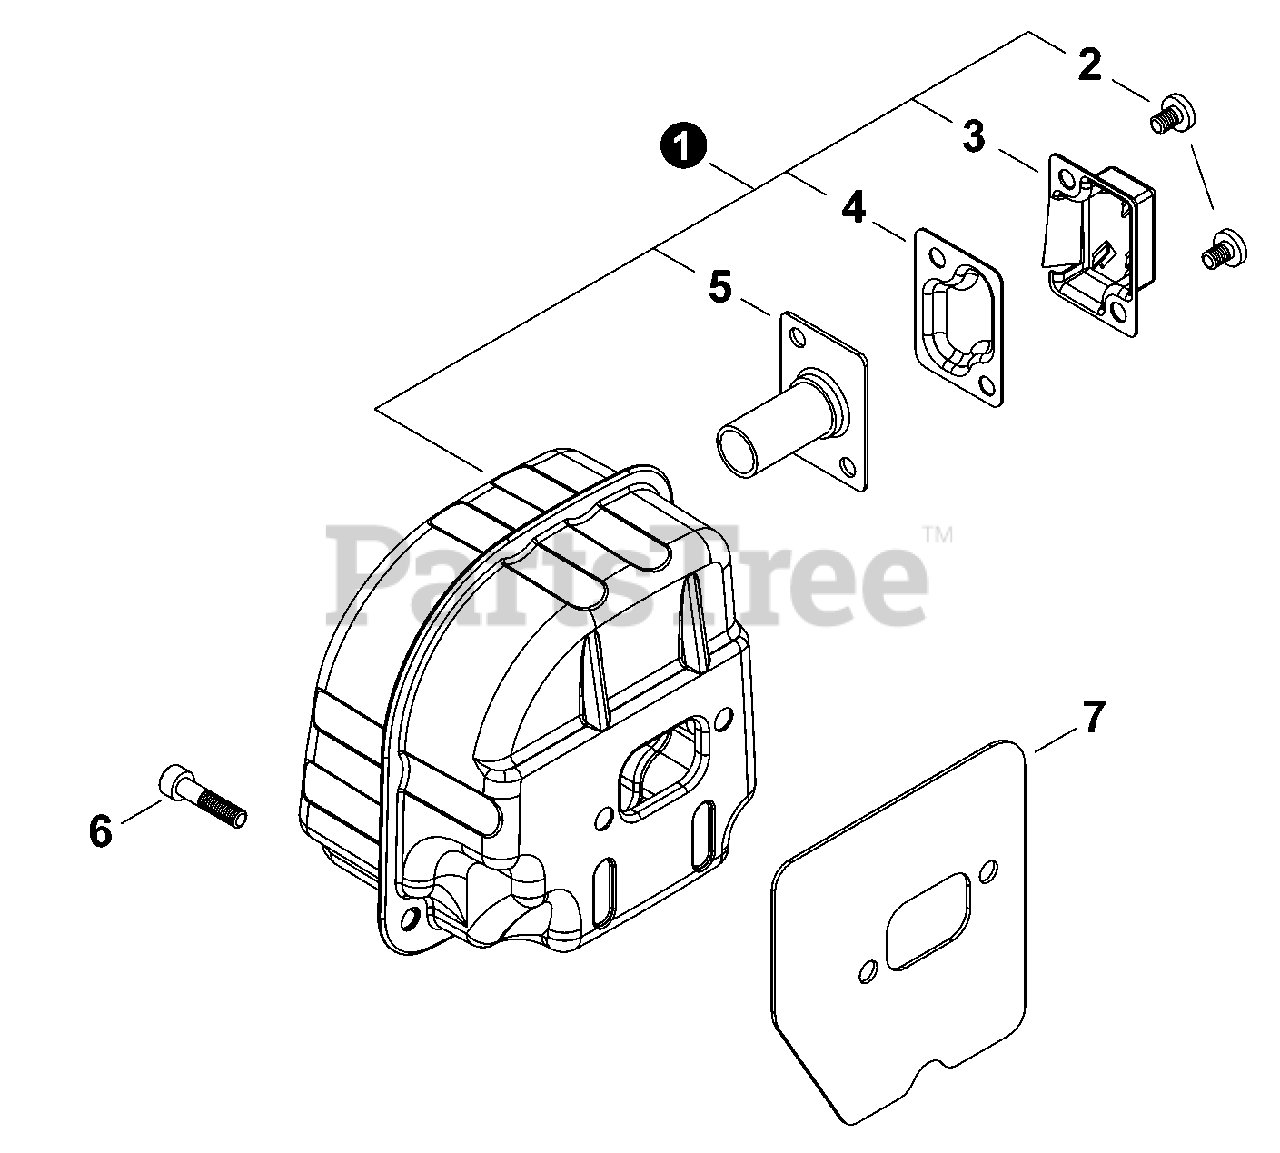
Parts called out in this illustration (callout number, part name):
1	MUFFLER ASSY
2	SCREW M4×6
3	OUTLET, EXHAUST
4	SCREEN, SPARK ARRESTER
5	GUIDE, EXHAUST
6	BOLT M5×18
7	GASKET, EXHAUST
